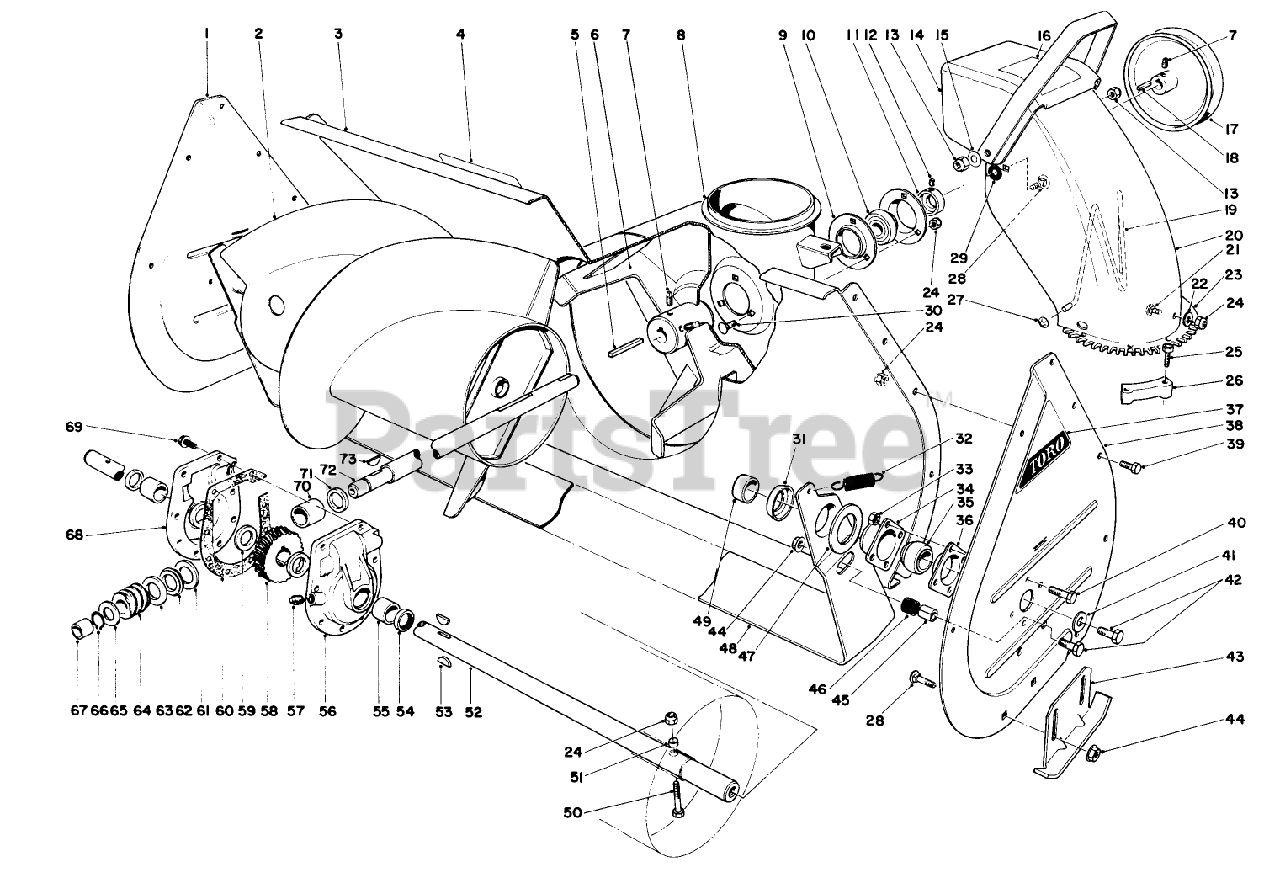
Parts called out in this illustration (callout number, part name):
7	SCREW-SET, SQH
8	CHUTE RING
9	BRG FLANGE
10	BALL BRG W/COLLAR
11	EXT LOCKING COLLAR
12	SCREW-HSH
13	NUT-LOCK, CONE
15	WASHER-BELLEVILLE
18	SQUARE KEY
19	WIRE-CHUTE
21	SCREW-CARR
22	WASHER-PLAIN
24	NUT-LOCK, NI
25	SCREW-SPECIAL
26	RETAINER-CHUTE
27	NUT-PUSH
28	SCREW-CARR
29	WASHER-RUBBER
30	BOLT-CARR
32	SPRING-TENSION
33	NUT-LOCK, CONE
34	BEARING-FLANGE, FRONT
35	BEARING
36	BEARING-FLANGE, REAR
39	SCREW-HH
40	SCREW-HH
41	WASHER
42	SCREW-HH
46	SCRAPER STOP CUSHION
47	SCRAPER BLADE SPACER
51	SPACER-HUB, AUGER
52	26 AUGER SHAFT
53	KEY-WOODRUFF
54	SEAL-OIL
55	BUSHING
57	PLUG-PIPE, SQH
58	GEAR-WORM, 27T
59	WASHER-THRUST
60	GASKET-CASE, GEAR
61	WASHER-THRUST
62	BEARING-THRUST
63	THRUST-WASHER
65	WASHER-THRUST
67	BUSHING
69	SCREW-HWH
70	BUSHING-SPECIAL
71	RING-QUAD
72	SHAFT-IMPELLER
73	KEY-WOODRUFF
